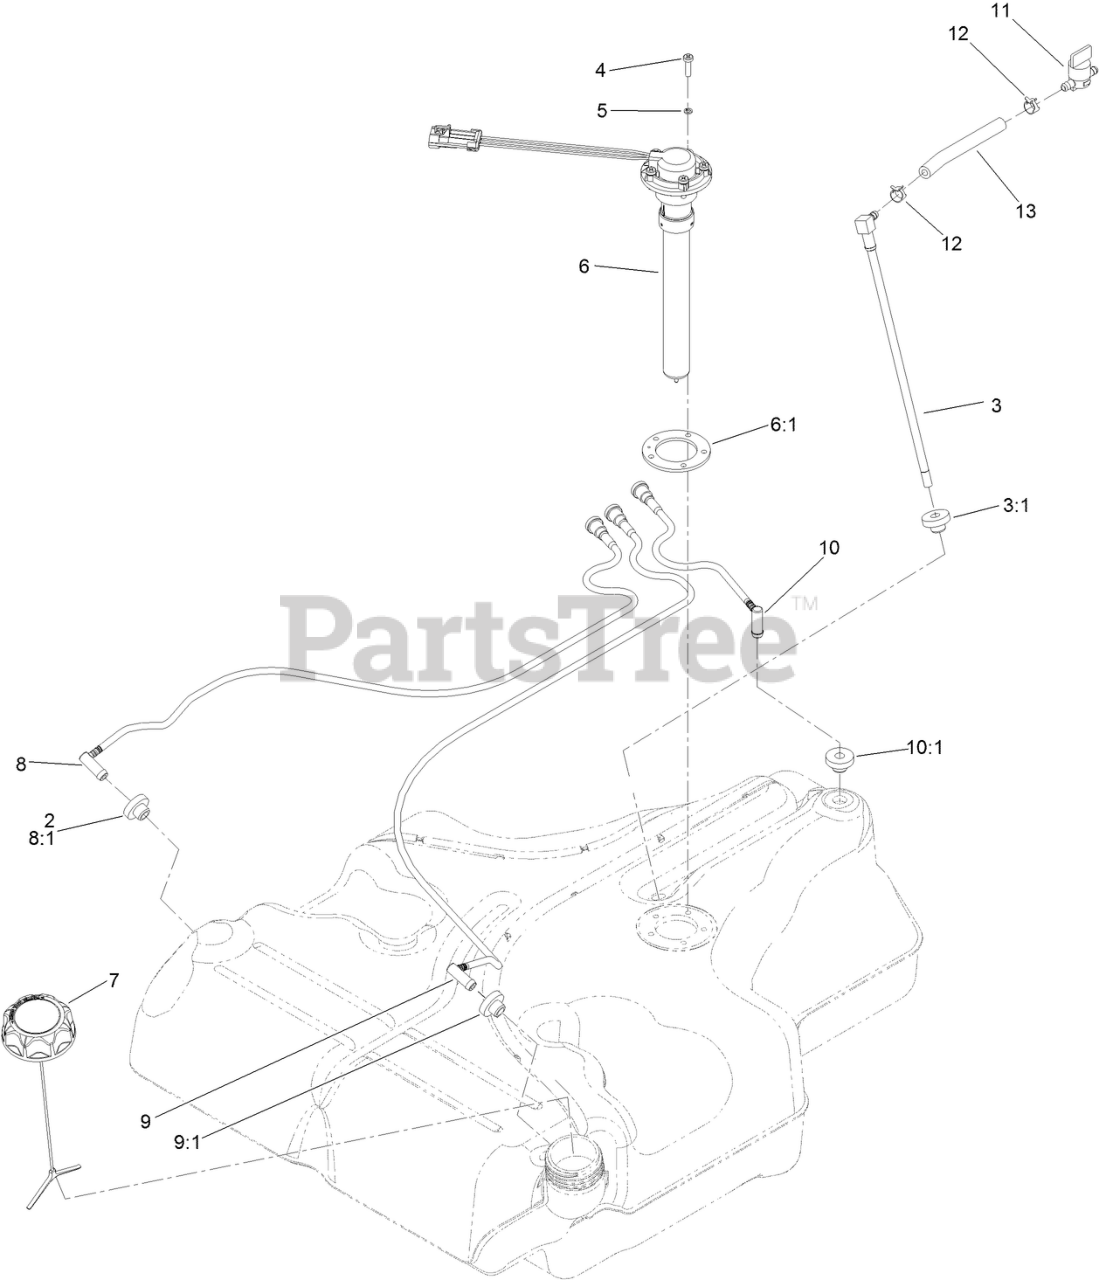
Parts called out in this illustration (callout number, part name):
2	BUSHING
3	FUEL LINE KIT (WITH GROMMET)
3:1	BUSHING
4	SCREW-PPH
5	WASHER-LOCK
6	FLOAT-SENDER, FUEL
6:1	Gasket-Sender
7	CAP-FUEL, RATCHETING
8	RH VENT LINE KIT (WITH GROMMET)
8:1	BUSHING
9	LH VENT LINE KIT (WITH GROMMET)
9:1	BUSHING
10	REAR VENT LINE KIT (WITH GROMMET)
10:1	BUSHING
11	VALVE-FUEL
12	CLAMP-HOSE
13	HOSE-FUEL
